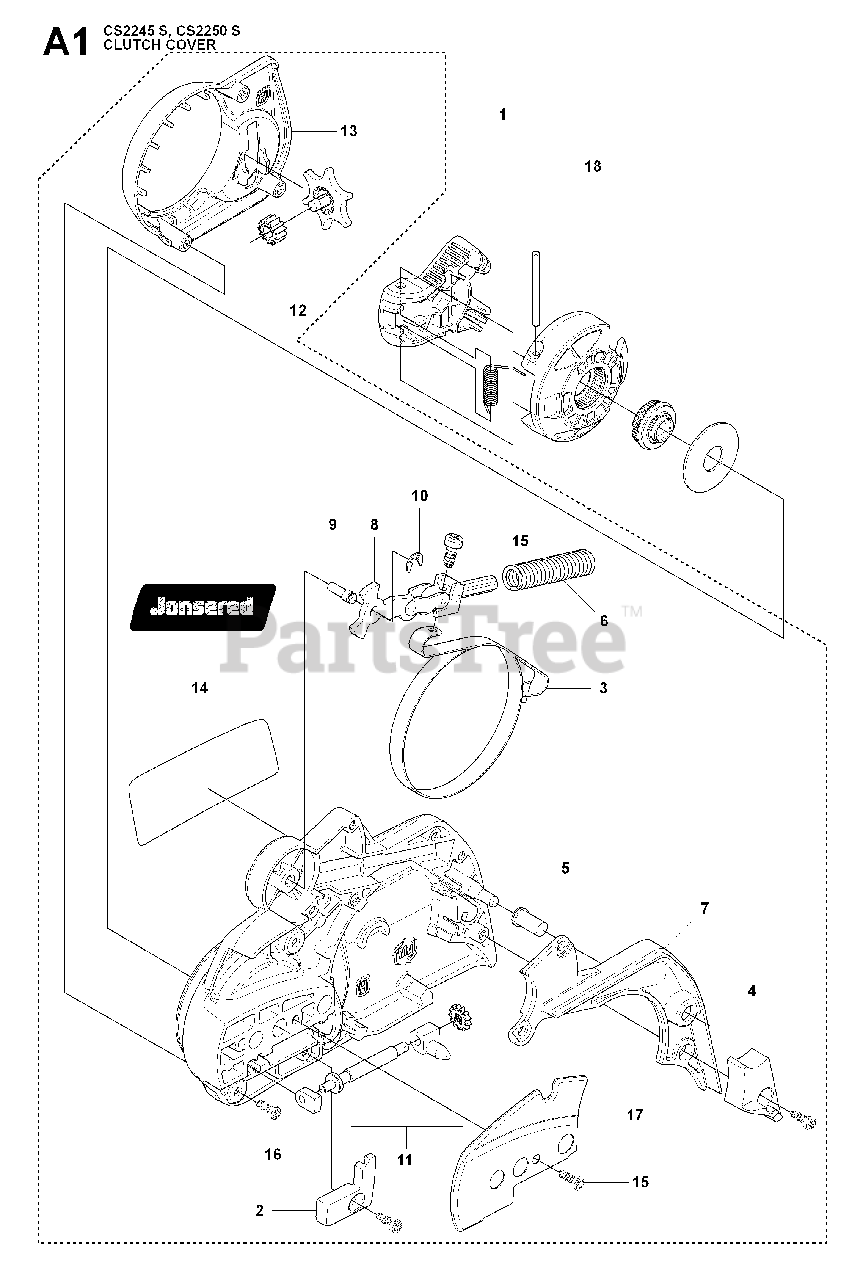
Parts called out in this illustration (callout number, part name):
1	CLUTCH COVER ASSY
2	%COVER
3	BRAKE BAND
4	WEAR GUARD, CHAIN
7	COVER, CHAIN BRAKE
11	CHAIN TENSIONER SCREW, COMP.
12	CHAIN TENSIONER WHEEL
16	RP BEARING SLEEVE
